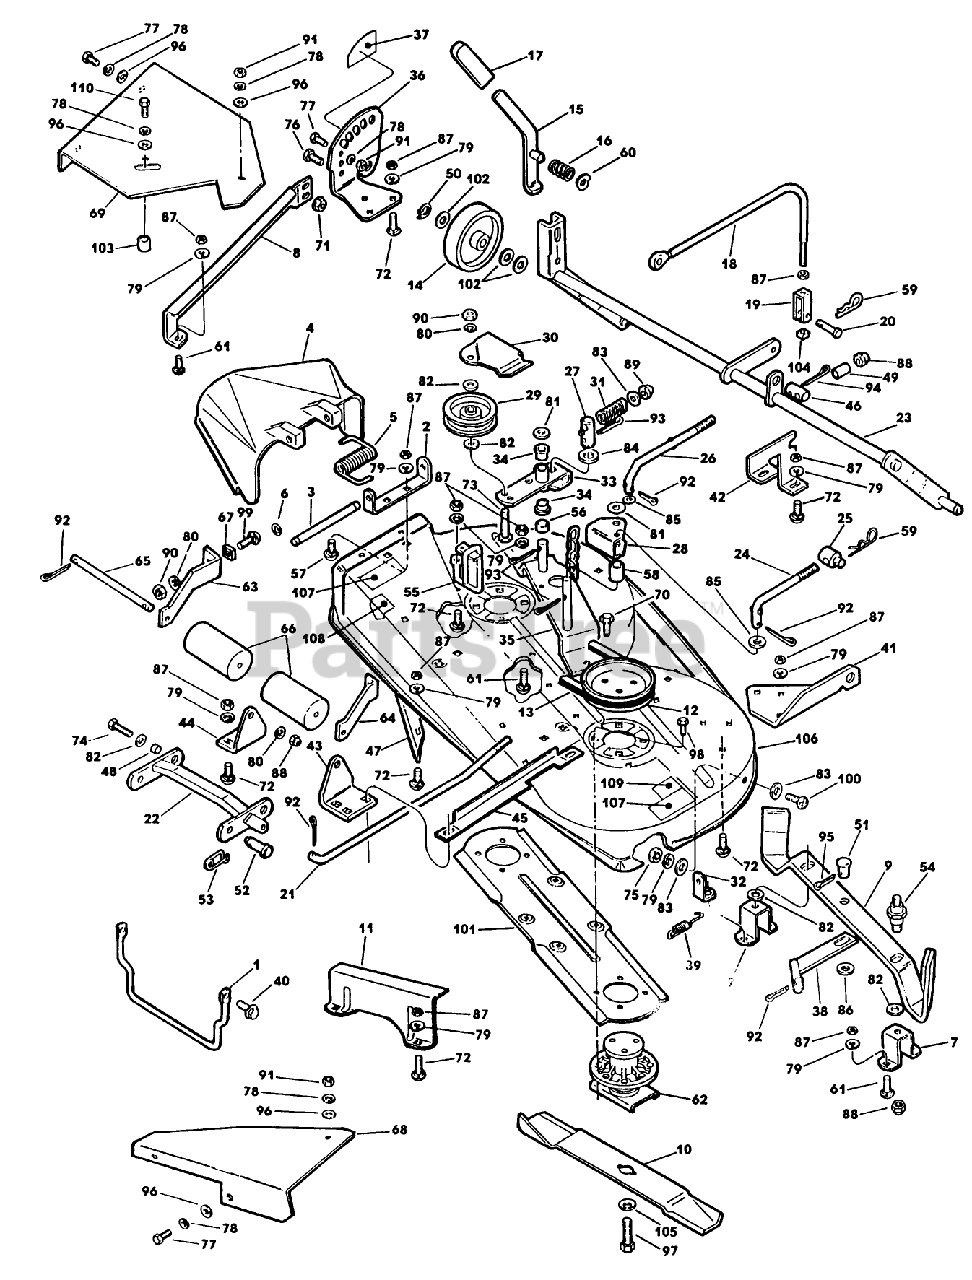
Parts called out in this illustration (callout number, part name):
3	SHAFT - CHUTE
4	EXTENSION -CHUTE
18	CABLE AY - LIFT
20	PIN-CLEVIS
29	PULLEY - 4"
34	BUSHING
43	BRACKET
50	RING - RETAINING
52	PIN CLEVIS
53	PIN - SAFETY
59	PIN-HAIR
72	BOLT - CARRIAGE
76	SCREW - HEX
77	SCREW-HH
88	NUT-LOCKING
97	SCREW - HEX CAP
98	SCREW-THD ROLL, HWH
102	WASHER - SHIM
105	Belleville Washer
